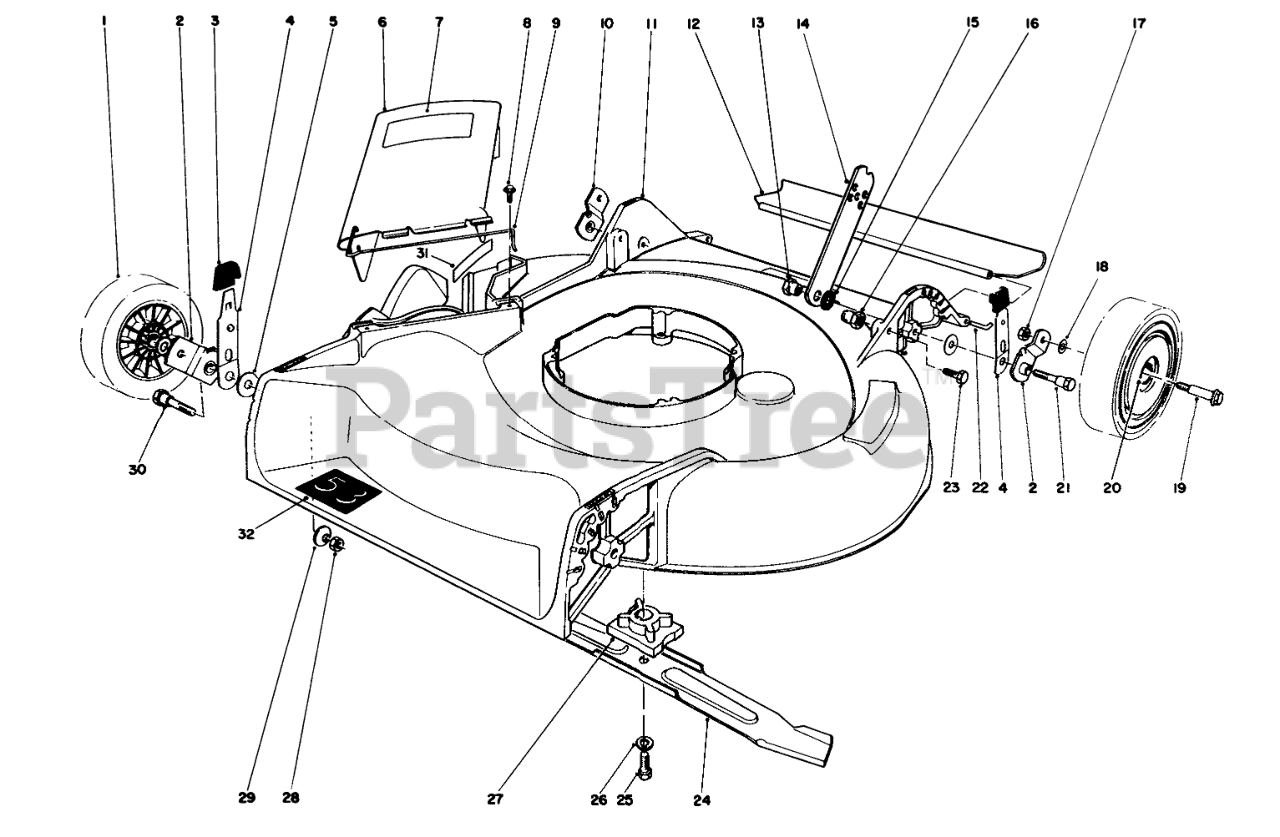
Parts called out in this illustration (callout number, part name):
1	Wheel & Tire Assembly (Incl. Ref. #20)
2	Pivot Arm
3	KNOB-ARM
4	SPRING ARM ASM
5	Washer
6	Deflector Assembly (Incl. Ref. #7)
7	Decal-Danger
8	SCREW-HWH
9	SPRING HINGE
10	Pivot Arm
11	Housing (Incl. Ref. #8)
12	REAR SAFETY SHIELD 21
13	HANDLE PIVOT NUT
14	HANDLE LATCH
15	SPACER
16	HANDLE PIVOT NUT
17	Nut
18	WASHER
19	BOLT-WHEEL
20	BUSHING
21	PIVOT SCREW
22	SHIELD ROD
23	SCREW-HH
24	Blade
25	SCREW-HH
26	WASHER-LOCK
27	BLADE RETAINER
28	NUT-LOCK, NI
29	WASHER-BELLEVILLE
30	5/16-18 PIVOT SCREW
31	DANGER DECAL
32	DECAL - 53
